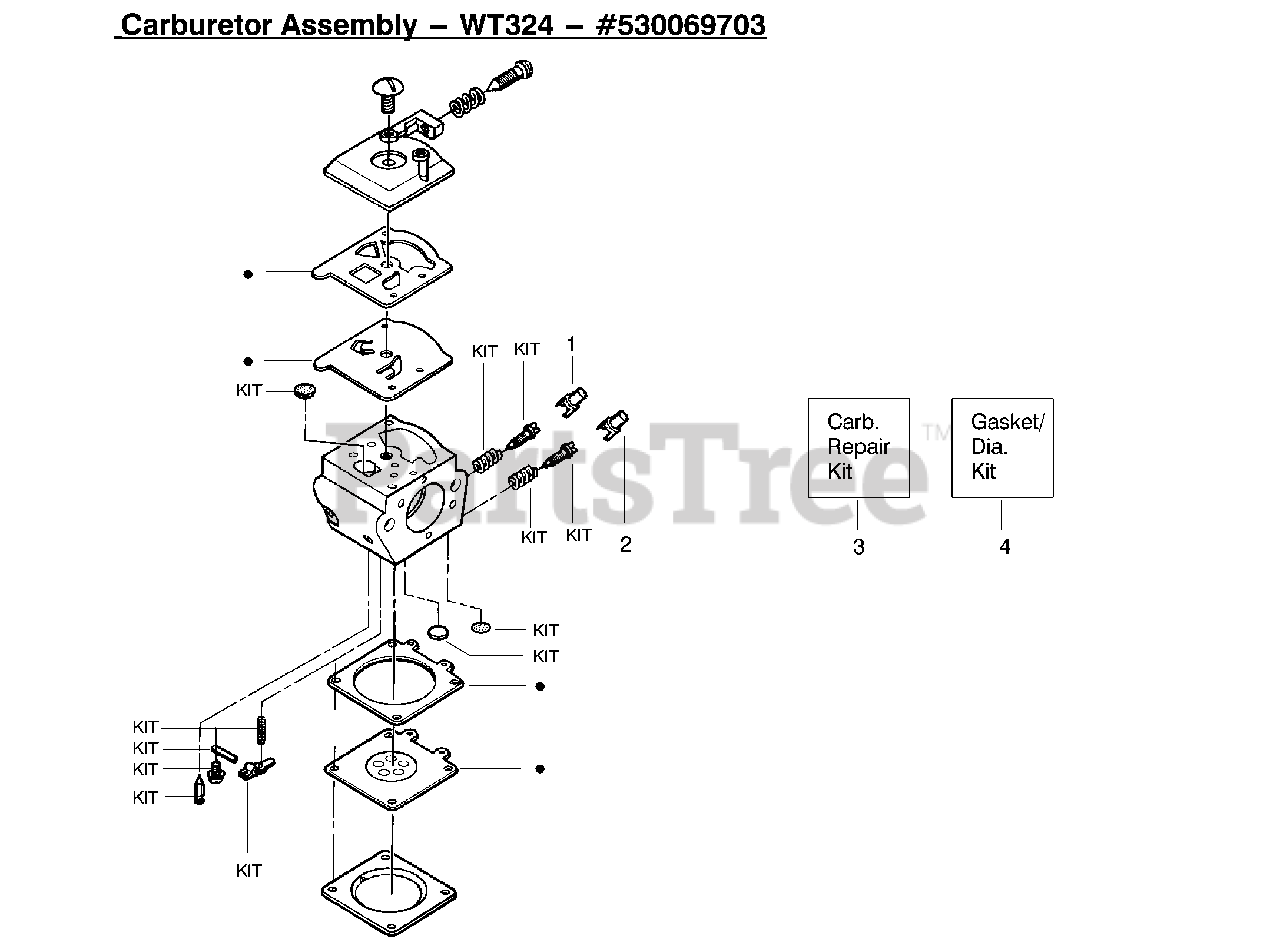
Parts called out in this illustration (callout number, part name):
1	Limiter Cap-High (brown)
2	Limiter Cap-Low (tan)
3	Carburetor Repair Kit
4	Gasket Diaphragm Kit
530069703	Carburetor Assembly - WT324
